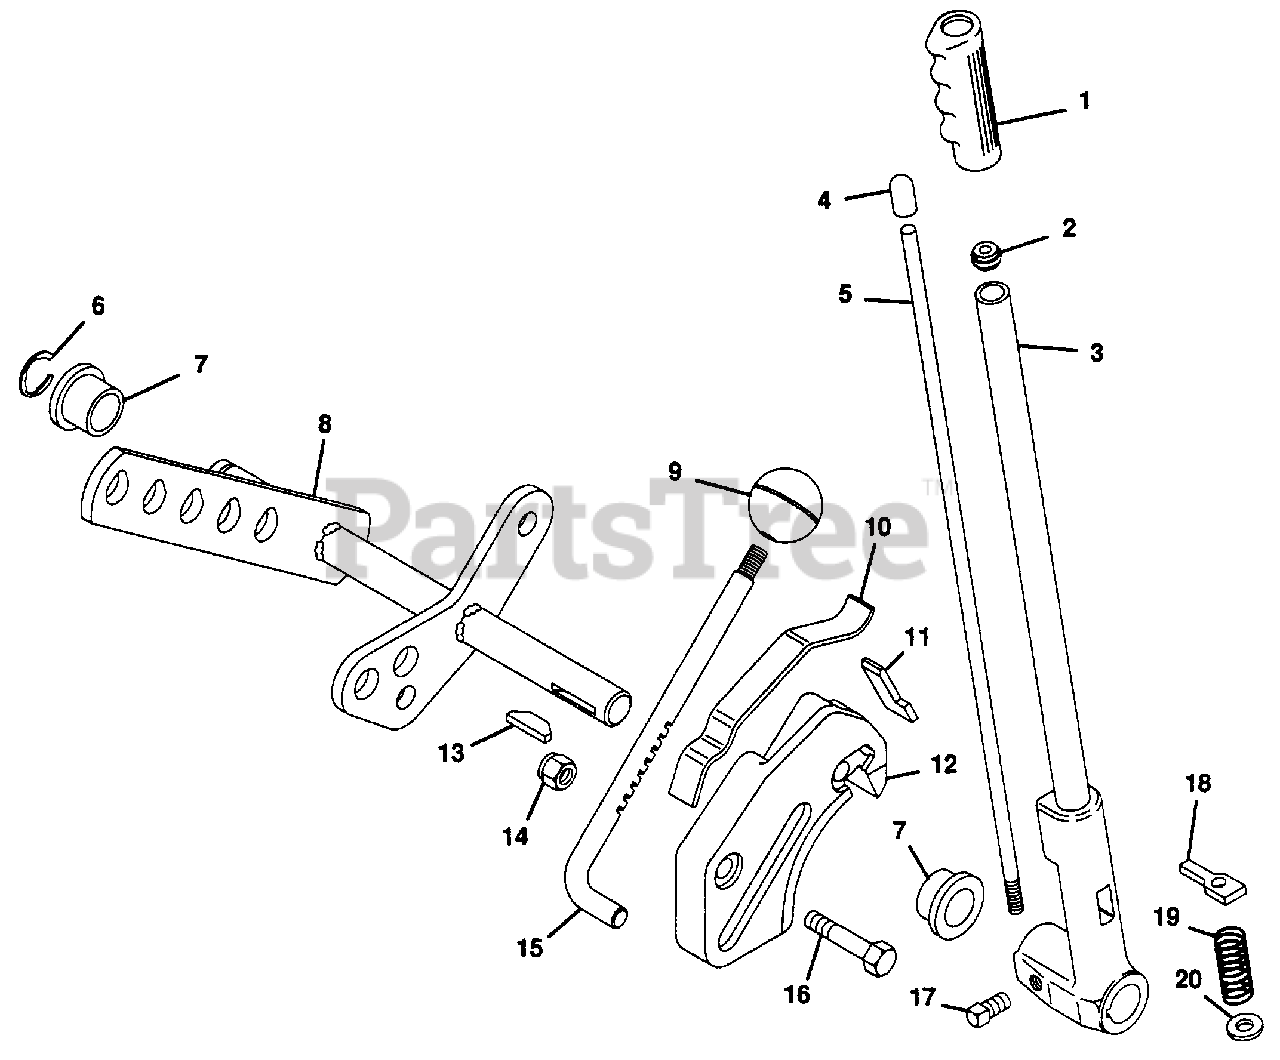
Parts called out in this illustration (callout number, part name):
1	GRIP, FLEX
2	GUIDE, PUSH ROD
3	ASSEMBLY, LEVER LIFT
4	TIP, PUSH ROD
5	ROD, LEVER PUSH
6	E-RING, 1.000 SHAFT
7	BUSHING, PIVOT
8	SHAFT, LIFT LEVER WELDMENT
9	KNOB, CONTROL
10	SPRING, STOP
11	STOP, LEVER
12	CASTING, LOCATOR
13	KEY, WOODRUFF .250X2.125 SOFT
14	NUT, LOCK 3/8-16
15	ROD, LEVER STOP
16	BOLT, HEX 3/8-16X1.25
17	SCREW, SET 3/8-16X.50 HSCP
18	PAWL, LEVER
19	SPRING, COMP. 2X.720X15.5 LB/IN
20	WASHER, SPECIAL FLAT .45X.99X.10
